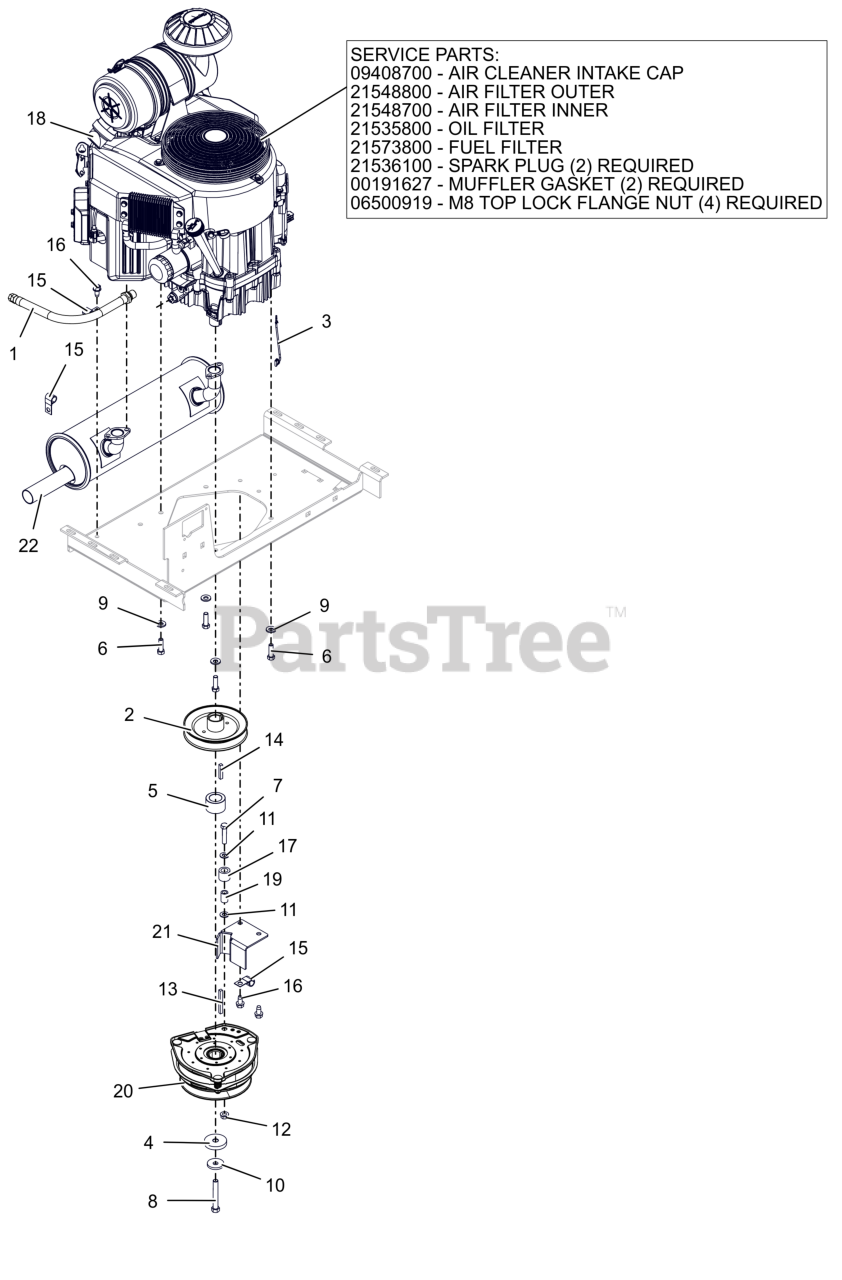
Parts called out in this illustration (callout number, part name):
1	HOSE, OIL DRAIN
2	WLDMT, TRANSAXLE DRIVE PULLEY
3	LEAD - STARTER SOLENOID
4	SPACER, .474/.459X2.00X.350
5	SPCR, 1.125 x 1.750 x 1.147
6	BLT, HEX .38-16X1.25 G5 ZCC NT
7	BLT, HEX .38-16X1.75 G5 ZCC
8	BLT, HEX 0.4375-20X3 G8 ZCC NT
9	WASHER, 3/8" SPRING DISC
10	WASHER, 7/16" SPRING DISK
11	WSHR,FLT .406X.812X.065 ZCC
12	NUT-LK-CTR-FLG .375-16 GF ZCC
13	KEY-SQ .25 X 2.50 X .25 SAE
14	KEY-SQ .25 X 1.50 X .25 SAE
16	SCR,TAP .375-16X.75 HWH TR ZCC
17	BUMPER,RUBBER .62X1.0X.88 LG
18	ENGINE, KAWASAKI FX850
18	CAP, AIR CLEANER INTAKE (2")
18	FILTER, OUTER
18	FILTER, INNER - KAW
18	FILTER,OIL - KAW
18	FUEL FILTER
19	BUSH.,S.391X.622X.950 ST
20	CLUTCH, OGURA GT3.5-AR04
21	WLDMT, CLUTCH STOP (BLACK)
22	MUFFLER, KAWASAKI FX850
